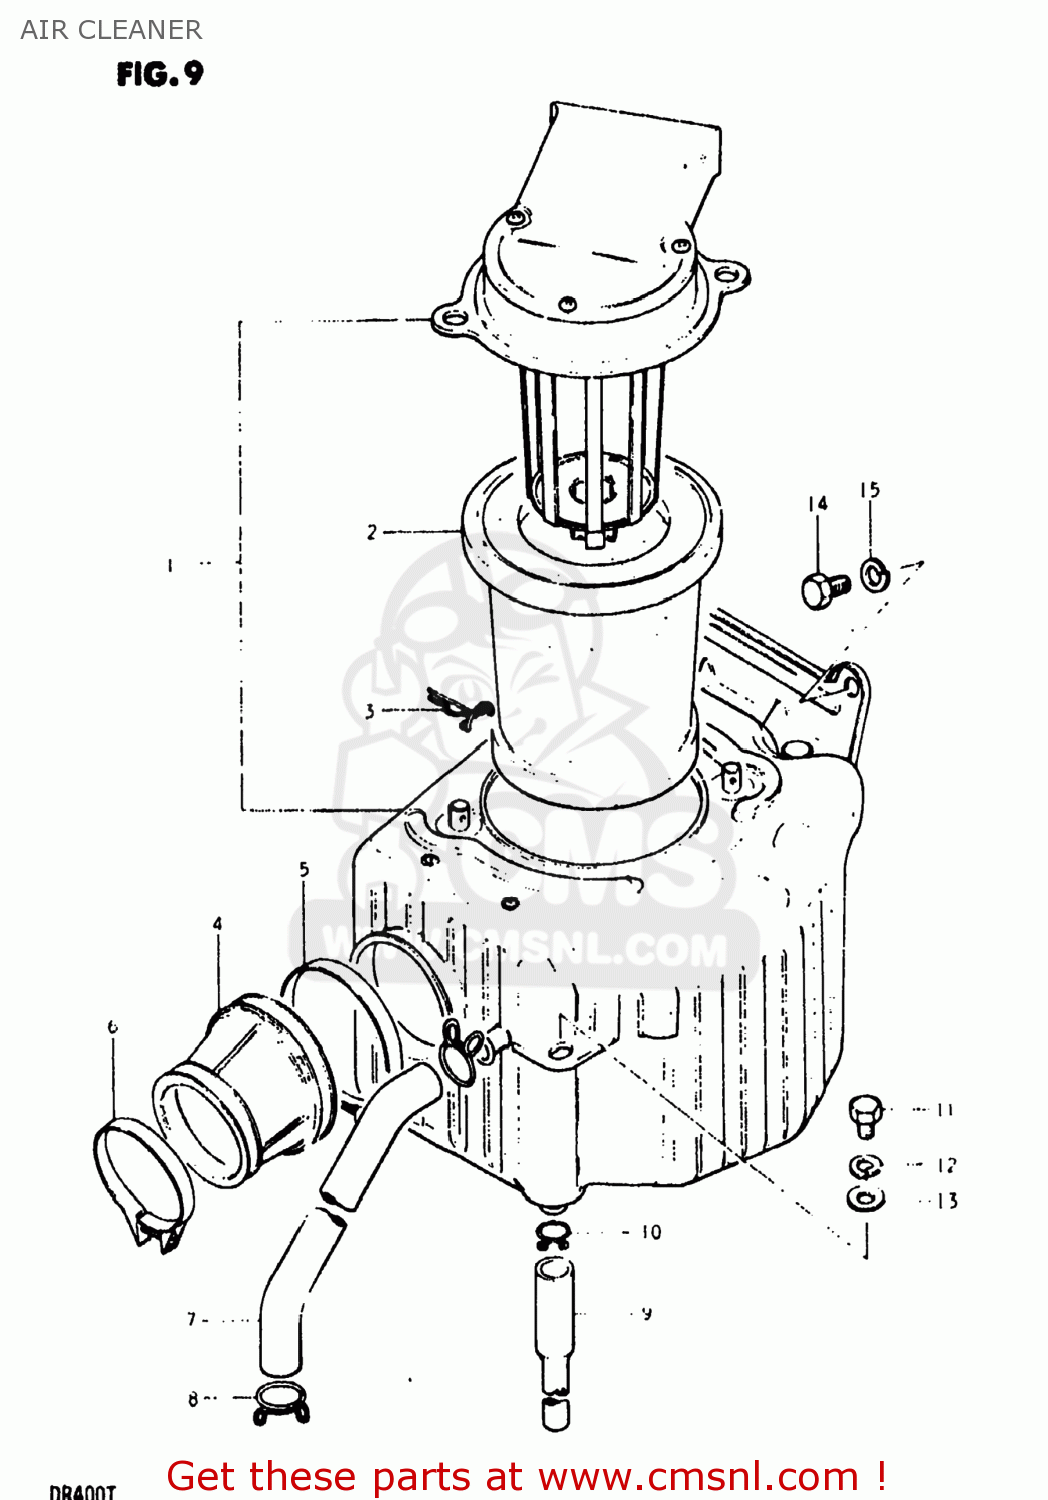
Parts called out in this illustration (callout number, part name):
1	CLEANER ASSEMBLY,AIR
2	FILTER
3	SNAP PIN,AIR CLEANER
4	TUBE,AIR CLEANER OUTLET
5	CLAMP
6	CLAMP
7	TUBE,BREATHER
8	CLIP,BREATHER TUBE
9	DRAIN TUBE
10	CLIP
11	BOLT, UPPER
12	LOCK WASHER
13	WASHER 6MM
14	BOLT
15	LOCK WASHER
